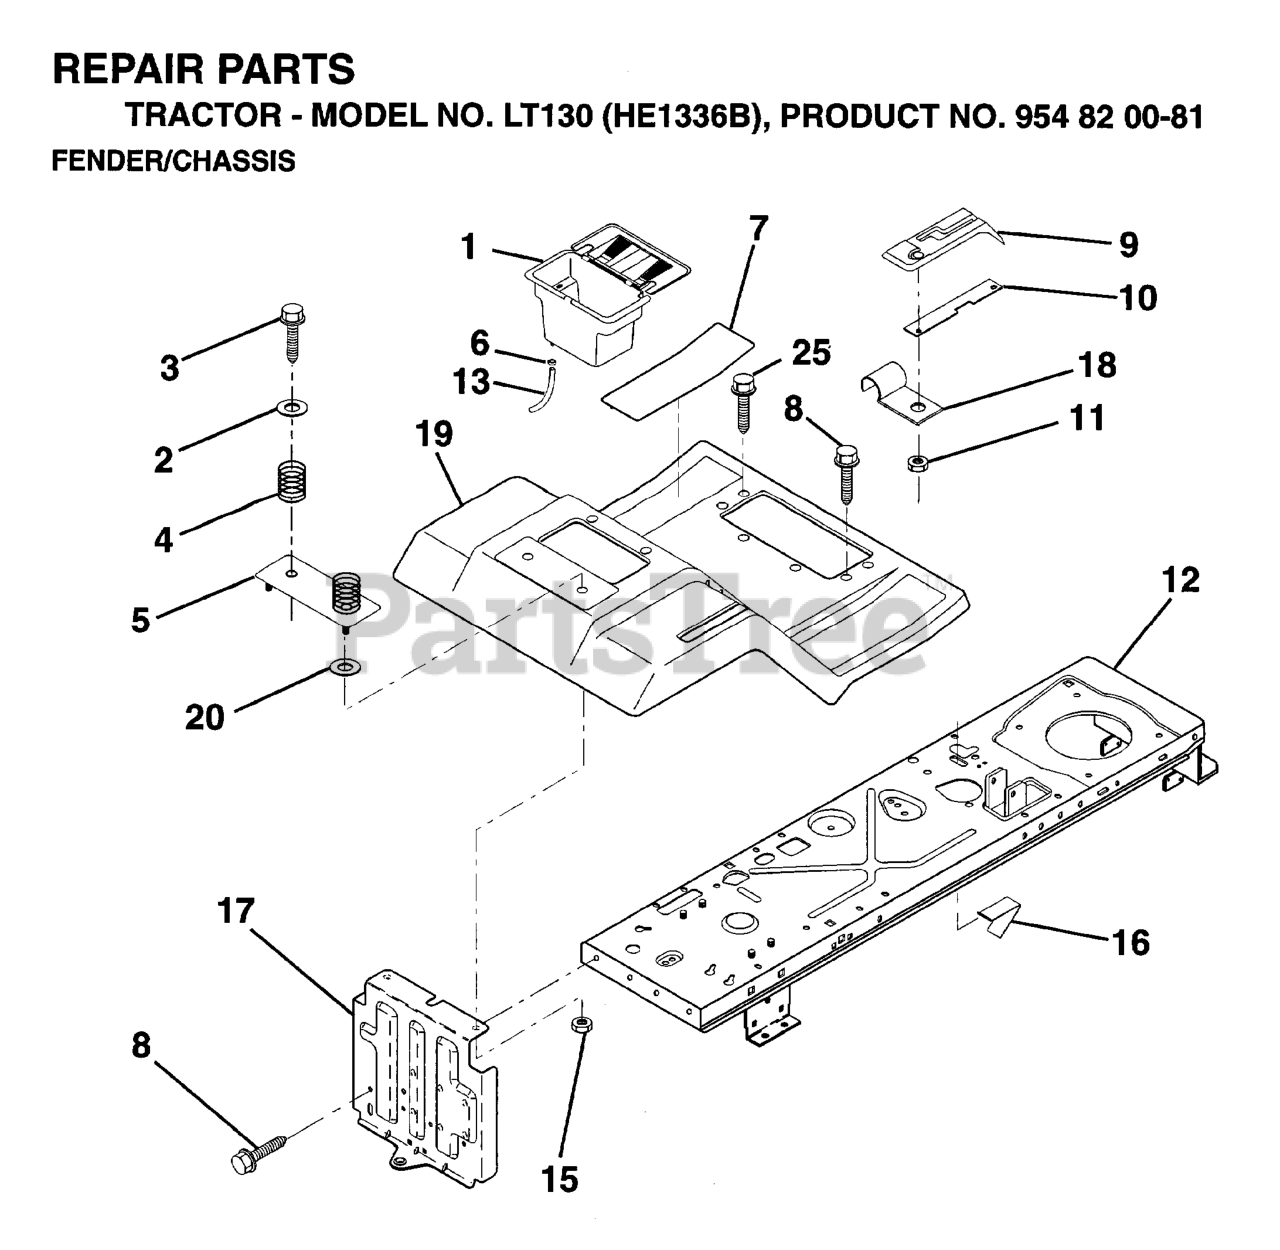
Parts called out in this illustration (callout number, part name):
1	BATTERY CASE
2	WASHER
3	SCREW
4	SPRING COMPRESSION
5	PLATE ASM BATTERY
6	HOSE CLAMP T
7	FOOTREST PAD
8	SCREW.THDROL.5/16-18X3/4.TTY
9	CONSOLE,SHT CONTR
10	BAR, SHIFT LOCK
11	NUT.PUSH.3/16
13	TUBE BATTERY DRAIN
15	Nut, Keps Blk Hex 1/4-20 UNC
16	SWITCH ACTUATOR
18	CLIP,INSULATOR
19	FENDER/FOOTREST
20	WASHER
25	Screw Hex Wsh Thdroll 5/16-18 x 1
